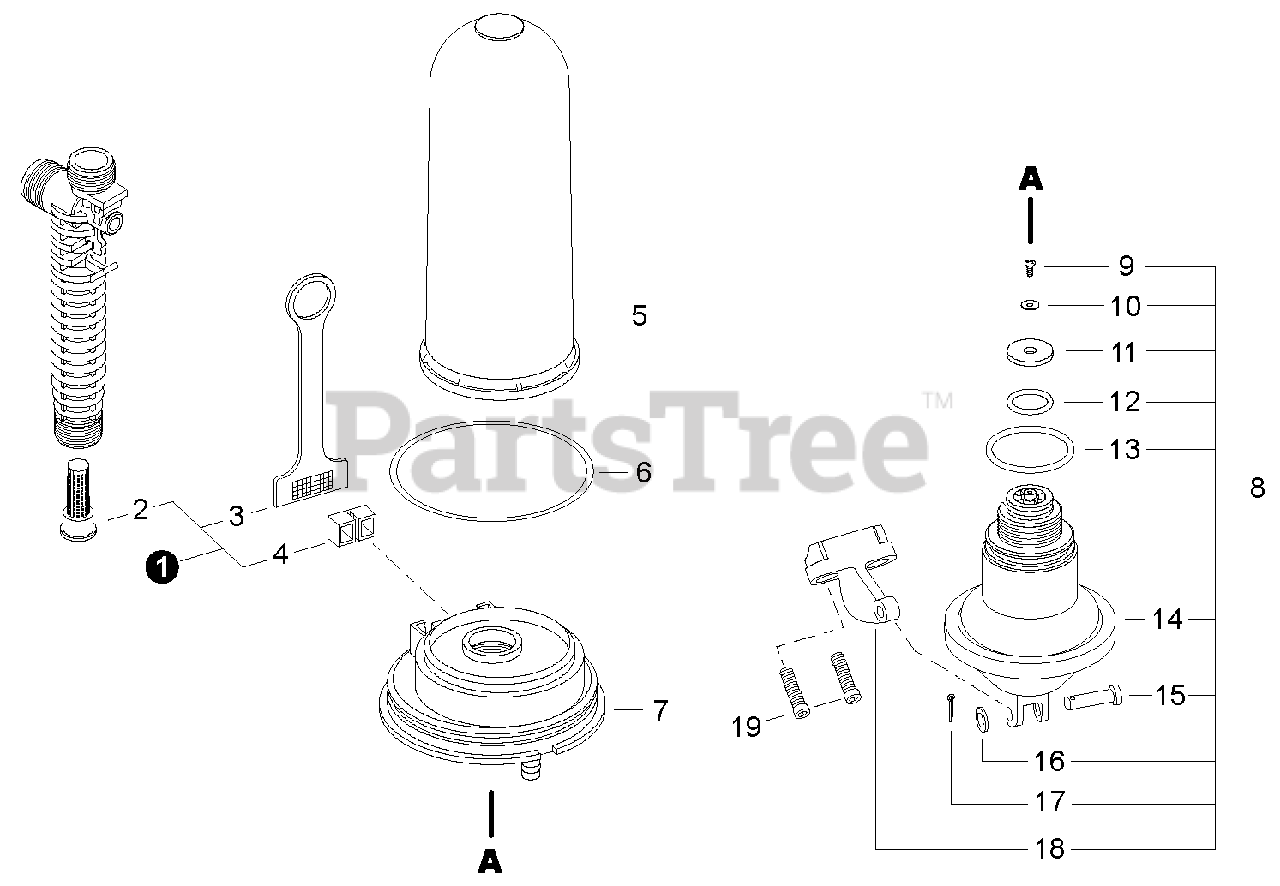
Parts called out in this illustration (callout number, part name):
1	FILTER KIT
2	FILTER, SPRAY GUN
3	FILTER, IN-TANK
4	FILTER, CARTRIDGE
5	CHAMBER, PRESSURE
6	O-RING, PRESSURE CHAMBER
7	BASE, PRESSURE CHAMBER
8	DIAPHRAGM PUMP ASSY
9	SCREW, CYLINDER
10	WASHER
11	SEAL, VALVE
12	O-RING, CYLINDER - SMALL
13	O-RING, CYLINDER - LARGE
14	PUMP, DIAPHRAGM
15	PIN, LEVER
16	WASHER
17	PIN, SPLIT
18	LEVER, PIVOT
19	SCREW, LEVER
